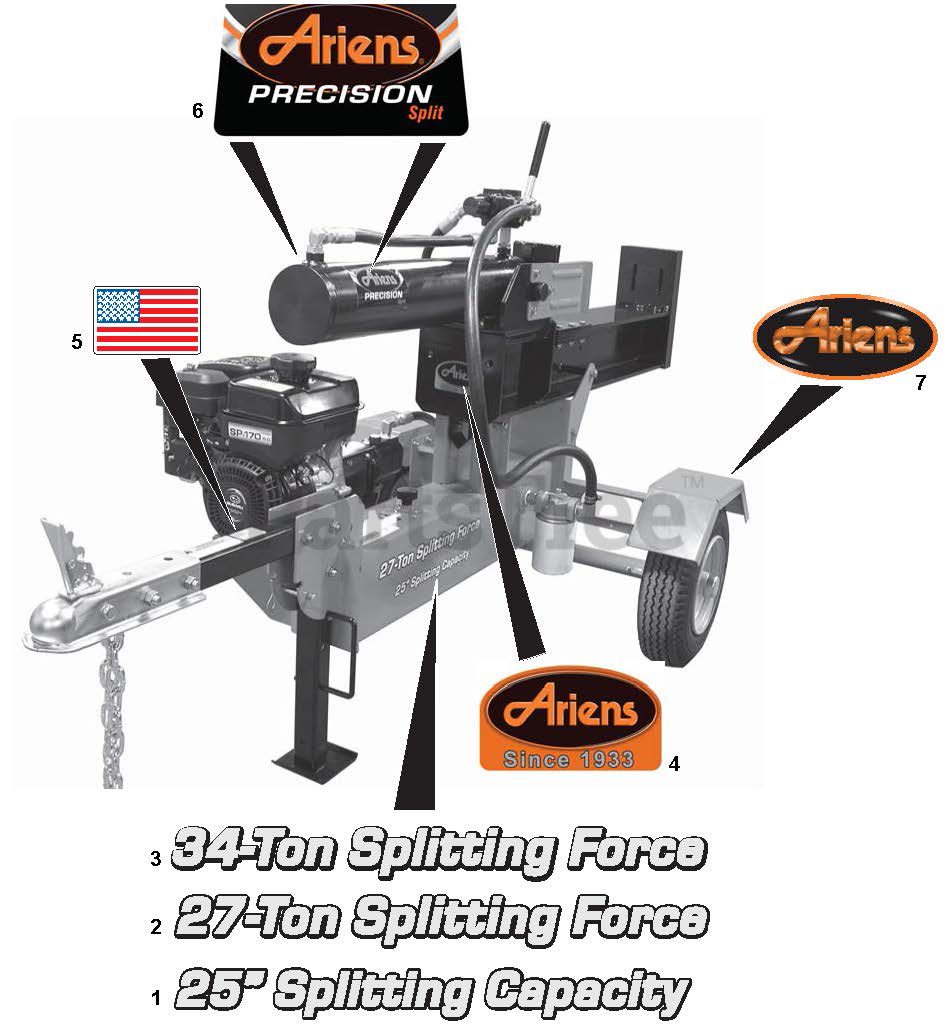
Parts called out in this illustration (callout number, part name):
1	DECAL, LOG SPLITTER-25" LENGTH
2	DECAL, LOG SPLITTER-27 TONS
3	DECAL, LOG SPLITTER-34 TONS
4	DECAL, ARIENS SINCE 1933 LG
5	DECAL, AMERICAN FLAG
6	DECAL, LOG SPLITTER-PRECISION
7	DECAL, ARIENS JEWEL (LARGE)
